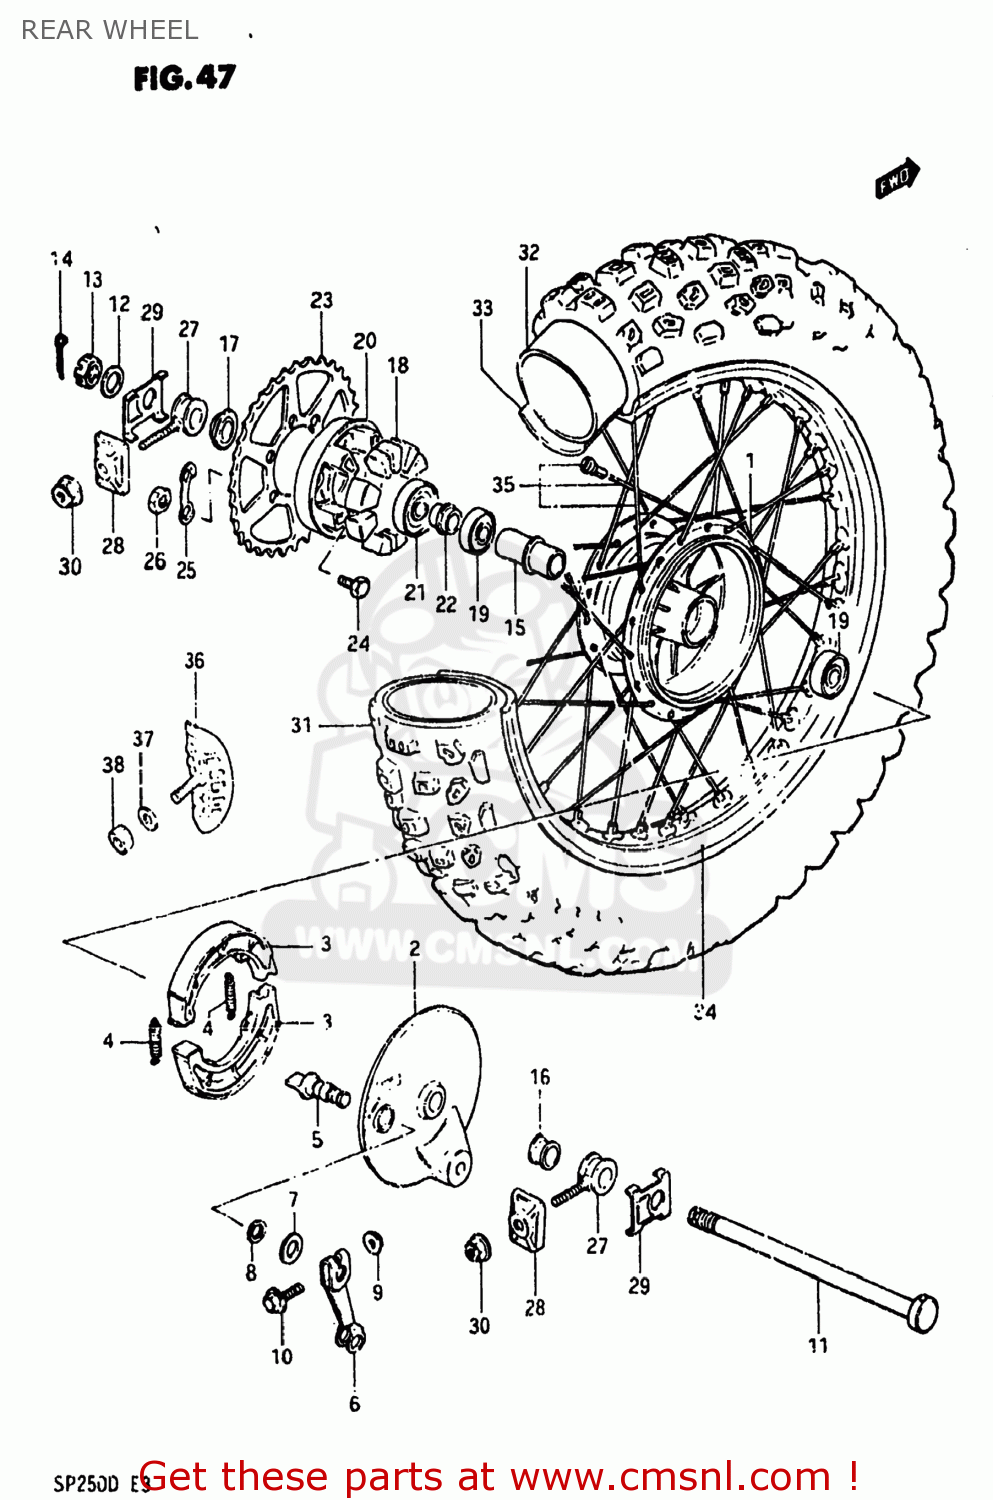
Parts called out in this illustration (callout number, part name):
1	DRUM,REAR HUB
2	PANEL,REAR HUB
3	SHOE,BRAKE
4	SPRING(L:34)
5	CAM,FRONT BRAKE
6	LEVER,REAR BRAKE CAM
7	WASHER (14.5X22X1.6)
8	O-RING (D:2.4 ID:13.8)
9	NUT
10	BOLT 6X35
11	AXLE,REAR
12	WASHER
13	NUT
14	PIN,COTTER
15	SPACER,REAR HUB BEARING
16	SPACER,REAR AXLE,RIGHT
17	SPACER,REAR AXLE
18	CUSHION,REAR DRUM
19	BEARING
20	DRUM,REAR SPROCKET MOUNT
21	BEARING
22	SPACER,REAR HUB BEARING
23	SPROCKET,RR(NT:42)
24	BOLT
25	WASHER
26	NUT
27	ADJUSTER,CHAIN
28	PLATE,CHAIN ADJUSTER
29	WASHER,CHAIN ADJUSTER GUIDE
30	NUT
31	TIRE
32	TUBE ASSEMBLY,WHEEL,INNER
33	PROTECTOR,WHEEL,INNER
34	RIM,REAR WHEEL
35	SPOKE ASSY,RR WHEEL
36	STOPPER,BEAD
37	WASHER
38	NUT
